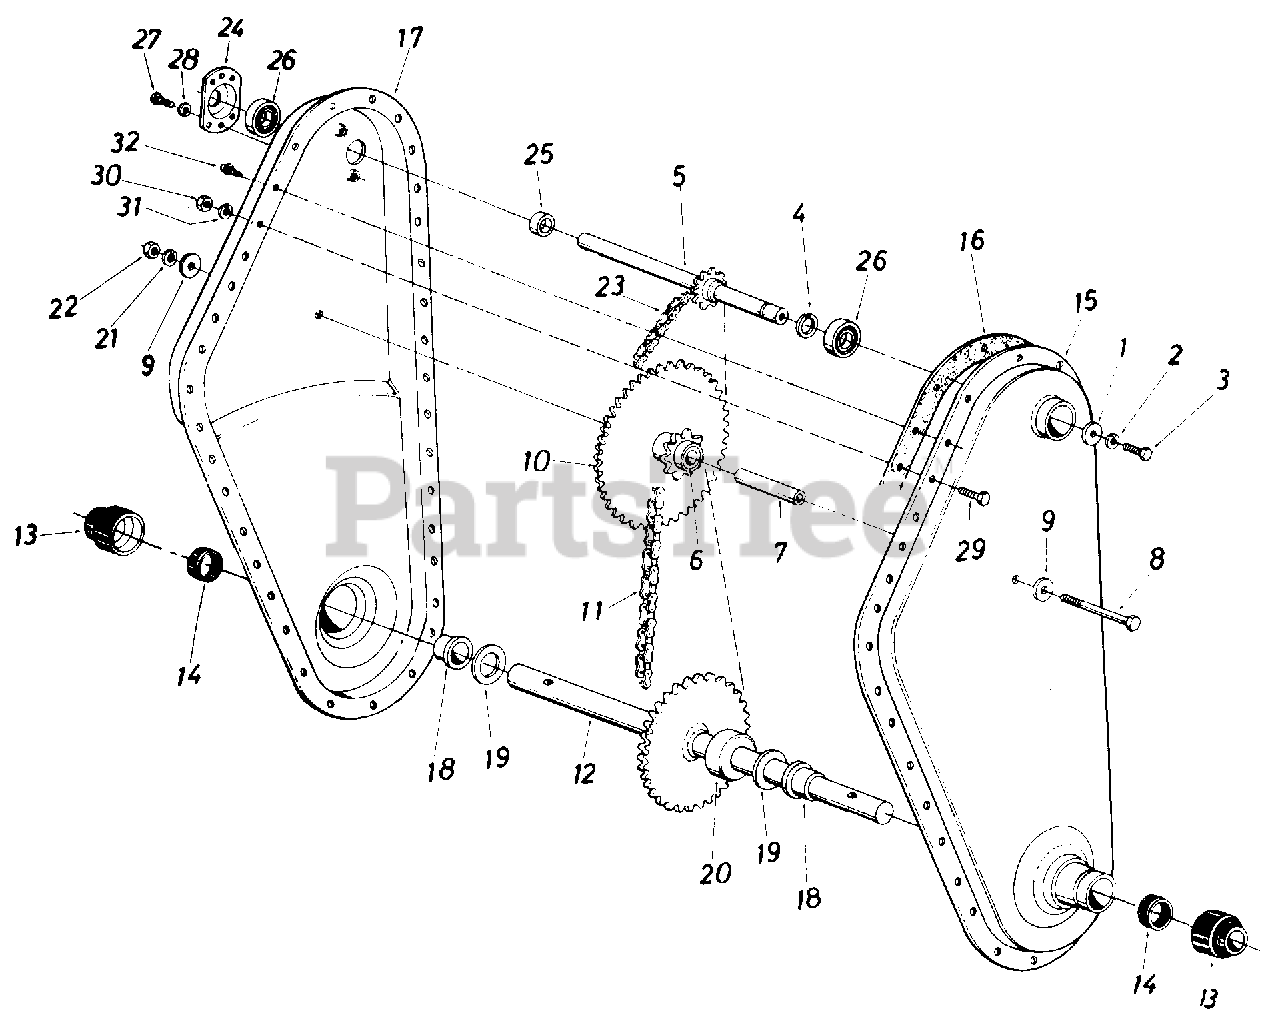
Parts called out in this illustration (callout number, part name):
1	Fl-Wash. 1/4" I.D. x .93" O.D. x .120
2	L-Wash. 1/4" I.D.*
3	Hex Bolt 1/4-28 x .62"0 Lg. w/Patch
4	External Snap Ring-5/8" Dia.
5	Input Shaft Ass'y.
6	Bearing 5/8" I.D. x 3/4" O.D. x 1.860" Lg.
7	Sprocket Hub Tubing 3/8" I.D. x 5/8" O.D. x 1.90
8	Hex Bolt 3/8-24 x 2.75" Lg.
9	Fl-Wash. 3/8" I.D. x 1.25" O.D. x .10
10	Sprocket Ass'y.
11	#50 Chain 5/8" Pitch x 46 Links Endless
12	Tine Shaft Ass'y.
13	Dust Cup
14	Seal Ring Single Lip, Springless
19	Fl-Thrust Wash. 1.0" I.D. x .03 Thk.
20	Step Spacer
21	L-Wash. 3/8" I.D.
22	Hex Nut 3/8-24 Thd.*
23	#35 Chain 3/8" Pitch x 52 Links Endless
24	Bearing Housing 1.38" I.D.
25	Spacer
26	Ball Bearing .625" I.D. x 1.38" O.D. x .437
27	Hex Wash. SF-Tap Scr. 1/4-20 x.50" Lg.
28	L-Wash. 1/4" I.D.
29	Hex Bolt 5/16-18 x .75" Lg.
30	Hex Nut 5/16-18 Thd.
31	L-Wash. 5/16" I.D.*
32	Hex Wash. SF-Tap Scr. 1/4-20 x.50" Lg.
14984-0638	HOUSING ASSEMBLY RH BLACK - MTD/TROY-BILT RED (0638)
